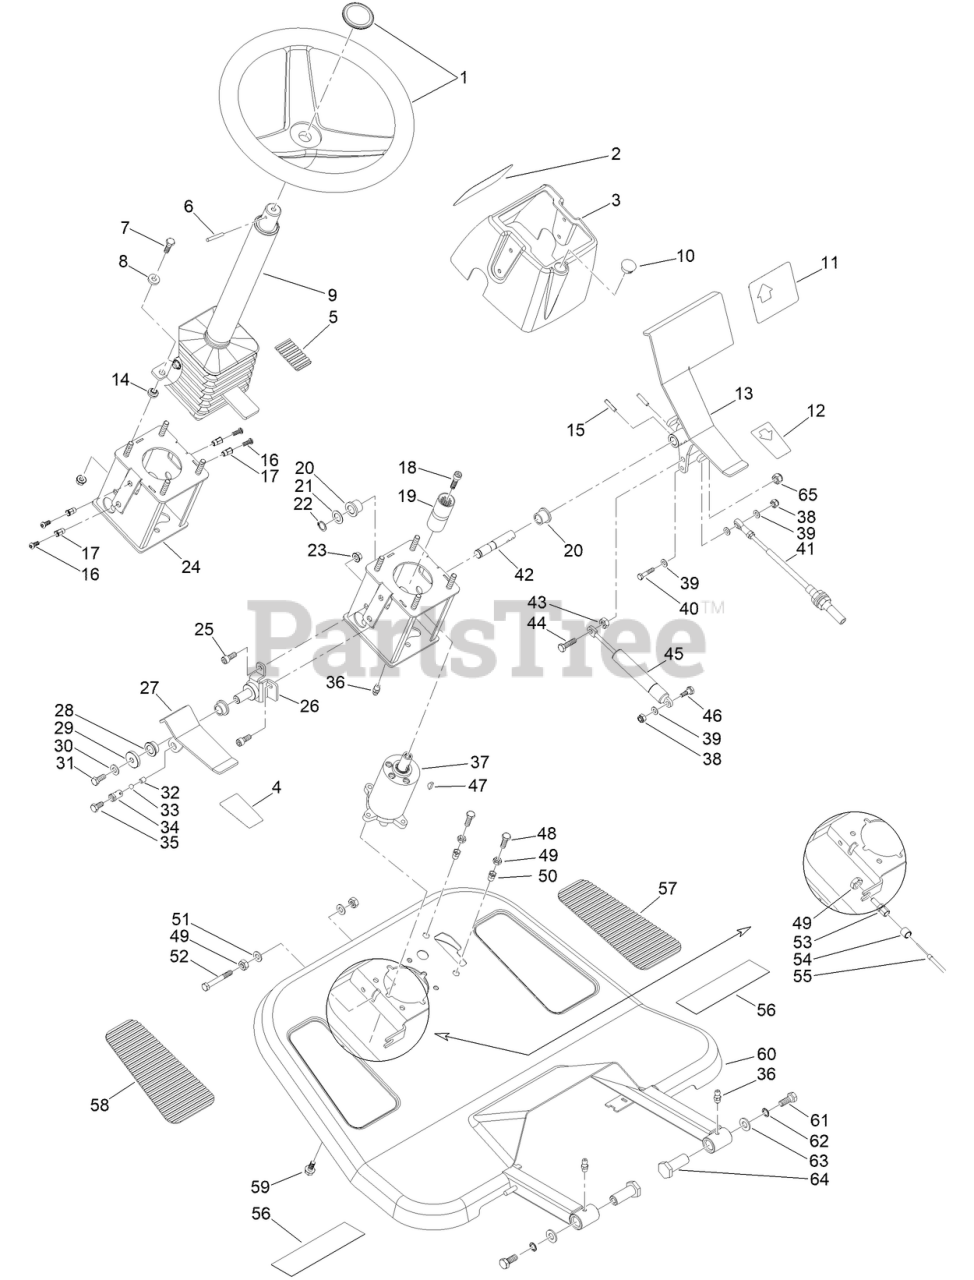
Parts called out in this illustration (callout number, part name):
1	WHEEL-STEERING
2	DECAL-LOGO, TORO
3	SHROUD, STEERING-COLUMN
4	TAPE, NON-SLIP
5	PAD, RUBBER
8	WASHER
9	STEERING COLUMN
10	PLUG, STEERING-CLMN
11	PAD-PEDAL, TRACTION
12	PAD-PEDAL, TRACTION
13	PEDAL, TRANSMISSION
14	BUSHING
17	INSERT-THREADED
19	HUB, STEERING VALVE
20	BUSHING
21	SPACER
22	RETAINER
24	SUPPORT, STEERING COLUMN
26	SUPPORT, DIFF LOCK PEDAL
27	PEDAL, DIFF LOCK
28	BUSHING
29	WASHER
30	WASHER
34	CLAMP, BRAKE CABLE
36	FITTING-GREASE
37	STEERING VALVE
39	WASHER
40	SCREW-HH
41	CABLE, TRANSMISSION
42	SHAFT, TRACTION PEDAL
45	ABSORBER-SHOCK
47	KEY-SHAFT
50	INSERT-THREADED
51	WASHER
53	REGISTER
54	CABLE-END, NIPPLE
55	CABLE, DIFF LOCK
56	GRIP STRIP
57	FOOTREST, RUBBER RH
58	FOOTREST, RUBBER LH
59	SCREW-HHF
60	PLATFORM
62	WASHER
63	WASHER
64	PIVOT, PLATFORM
